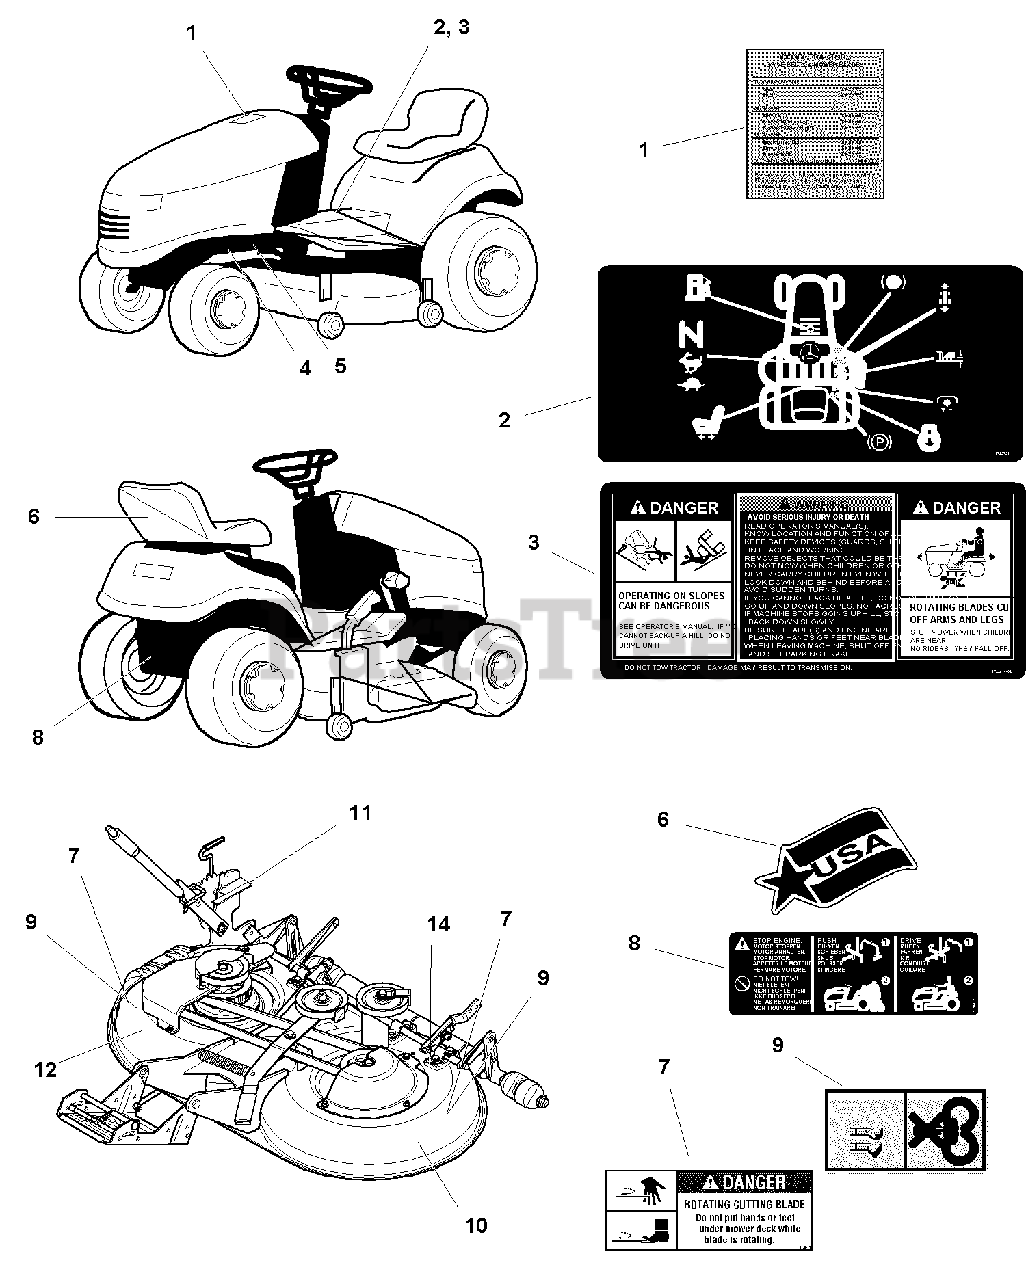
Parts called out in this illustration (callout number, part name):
1	DECAL, Belts & Mower Blades
2	DECAL, Operating Instructions
3	DECAL, Safety Instructions
4	DECAL, Patent (Not Serviced)
5	DECAL, Serial Number (Not Serviced)
5	DECAL, CE & Serial Number Export (Not Serviced)
6	DECAL, USA Logo
7	DECAL, Danger Rotating Cutting Blade, 40"
8	DECAL, Transmission Relese Valve, Hydros Only
9	DECAL, Danger Rotating Cutting Blade, 40" (Export)
10	DECAL, Free Floating Mower
11	DECAL, Height of Cut
14	DECAL, OPEI (Not Serviced)
